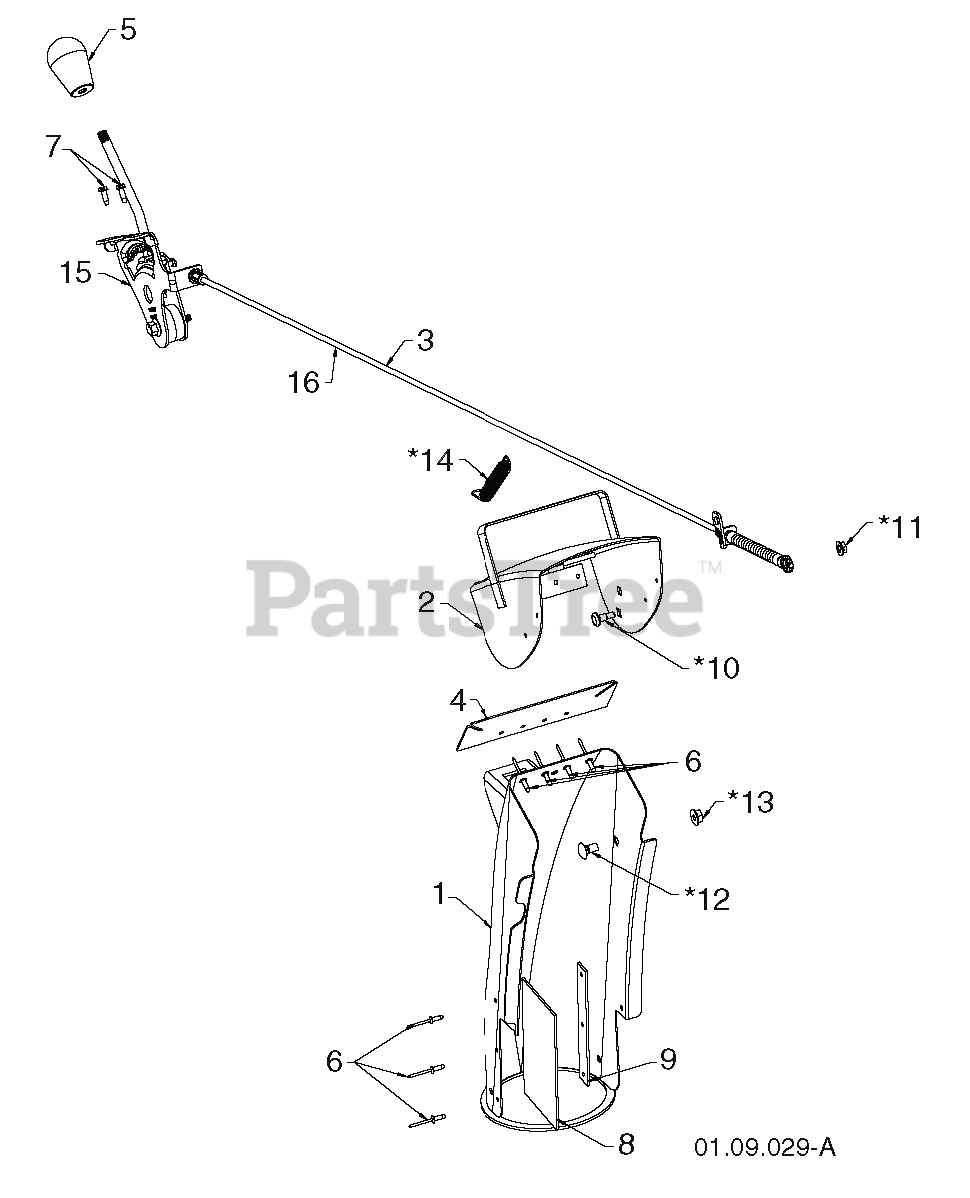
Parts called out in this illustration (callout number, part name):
1	CHUTE.WELDMENT.SNOW.ORANGE
2	DEFLECTOR.WELDMENT.PNT.ORANGE
3	RP CRTL.ASM.DEFLECTOR.BLACK.SN
4	SEAL.DEFLECTOR
5	KNOB.OVERMOLD.DS.HUSQVARNA/BLK
6	RIVET BLIND
8	SHIELD.SNOW.CHUTE
9	STRAP.SHEILD.RETAINER
15	RP CNTRL.HEAD.ASSEM.DEFLECTOR
16	RB SERVICE.CHUTE.DEF.CBL.BLK
